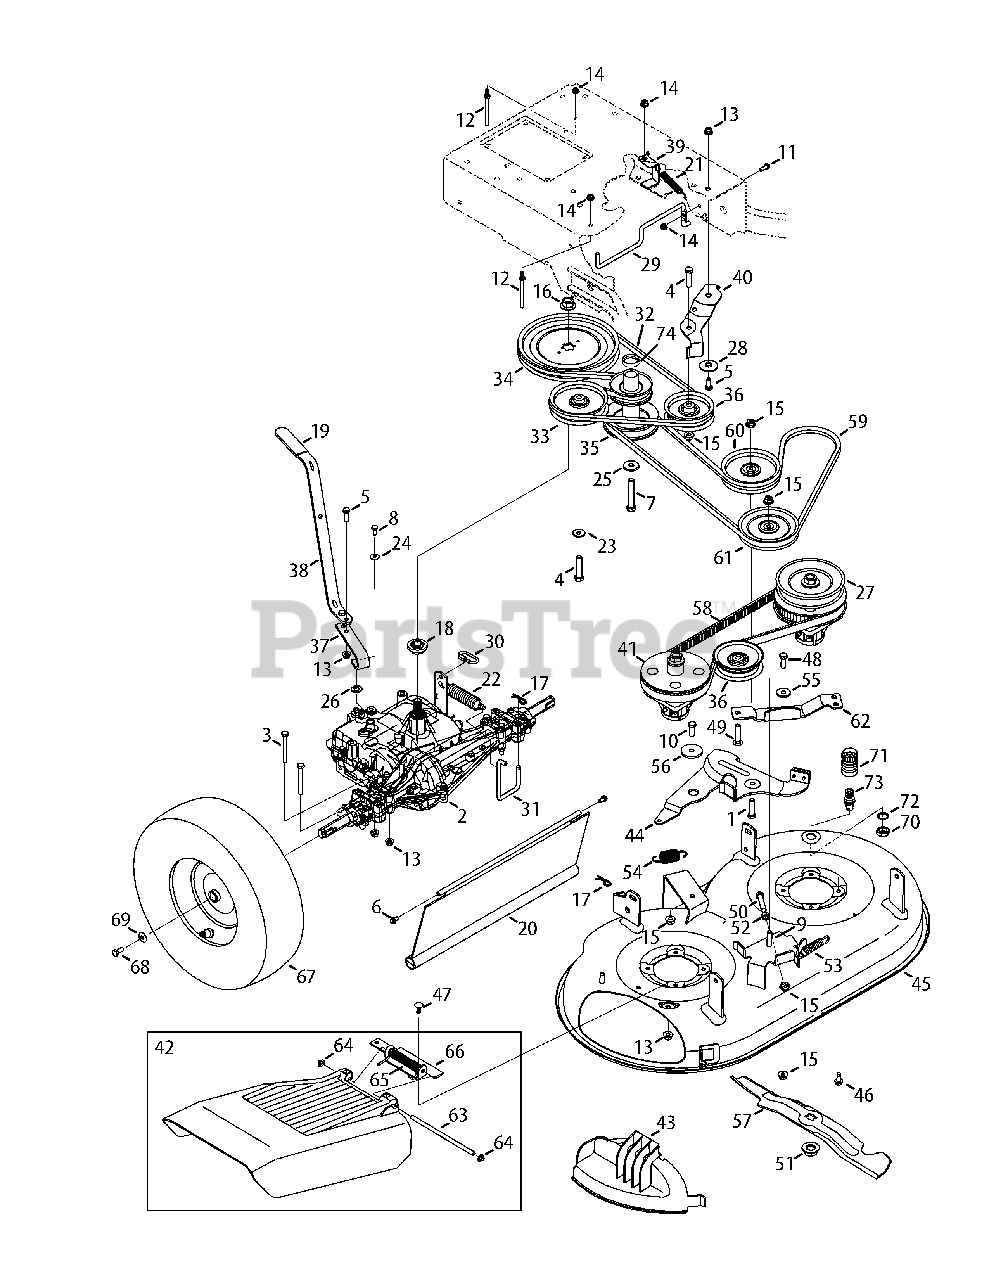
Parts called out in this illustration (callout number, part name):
1	Hex Head Cap Screw, 3/8-16 x 1.75
2	4 Speed Drive Assembly, Tecumseh
3	Hex Head Cap Screw, 5/16-18 x 2.75
4	Hex Head Cap Screw, 3/8-16 x 1.75
5	Hex Head Cap Screw, 5/16-18 x 1.00
6	Screw, 1/4-15 x 0.50
7	HHCS, 7/16-20 x 2.75
8	Hex Head Cap Screw, 1/4-28 x .625
9	Hex Head Cap Screw, 3/8-16 x 1.50
10	Hex Head Cap Screw, 3/8-16 x 1.25
11	Hex Head Cap Screw, 1/4-20 x .75
12	Belt Keeper, .25 DIA X 3.0
13	Flangelock Nut, 5/16-18
14	Flangelock Nut, 1/4-20
15	Flangelock Nut, 3/8-16
16	Flange Nut, 9/16-18
17	Click Pin, .092 x 1.64 LG
18	Spline Pulley Hub, 5/8
20	Trailshield, 8.35 x 19.17
21	Extension Spring, Wheel Drive
22	Extension Spring, Brake
23	Washer, Spring, .401 x .870 x .063
24	Washer, Bell, .265 x .75 x .062
25	Washer, Flat, .450 x 1.250 x .164
26	Washer, Flat, .39 x .87 x .06
27	Drive Spindle Assembly
28	Spacer, Shoulder, .5000 x .1475
29	Belt Keeper Rod
30	Coupling Link, 3/16
31	Brake Spring Mounting Rod
32	V Belt. 4L 64.2
33	Idler Pulley, 4.25 DIA
34	Flat Sheave, DIA 7.75
35	Engine Pulley, 3.20 x 4.35 DIA
36	Idler Pulley, 3.50 DIA
37	Lower Shaft Lever
38	Upper Shaft Lever
41	Spacer Spindle Assembly
42	Chute Deflector Assembly
43	Mulch Cover
44	Idler Arm Assembly
45	Deck Assembly
46	Screw, 5/16-18 x .750
47	Bolt, Carriage, 5/16-18 x .750
48	Hex Head Cap Screw, 3/8-16 x 1.00
49	Screw, Carriage, 3/8-16 x 1.75
50	Hex Head Cap Screw, 3/8-16 x 2.00
51	Flange Nut, 5/8-18
52	Hex Nut, 3/8-16
53	Extension Spring, Timing Belt
54	Extension Spring, Deck Brake
55	Shoulder Spacer, .625 ID x .169
56	Shoulder Spacer, .8840 x .190
57	2 in 1 Blade
58	Timing Belt, .315 x .787
59	Aramid V Belt, 72.2
60	Idler Pulley, 4.25" DIA
61	Idler Pulley, V-Type, 5.0 DIA
62	Timing Idler Bracket
63	Deflector Pin
64	Push Cap
65	Deflector Torsion Spring
66	Deflector Hinge Bracket
67	Wheel, 16 x 4 x 8
68	Hex Screw, 5/16-24 x .750
69	Washer, Bell, .340 x .872 x .060
70	Nut, Hex, M16-1.5
71	Water Nozzle Adaptor
72	Washer, Lock, 5/8
73	Deck Water Nozzle
74	Spacer, 1.0 x 1.28 x .31 (420CC)
